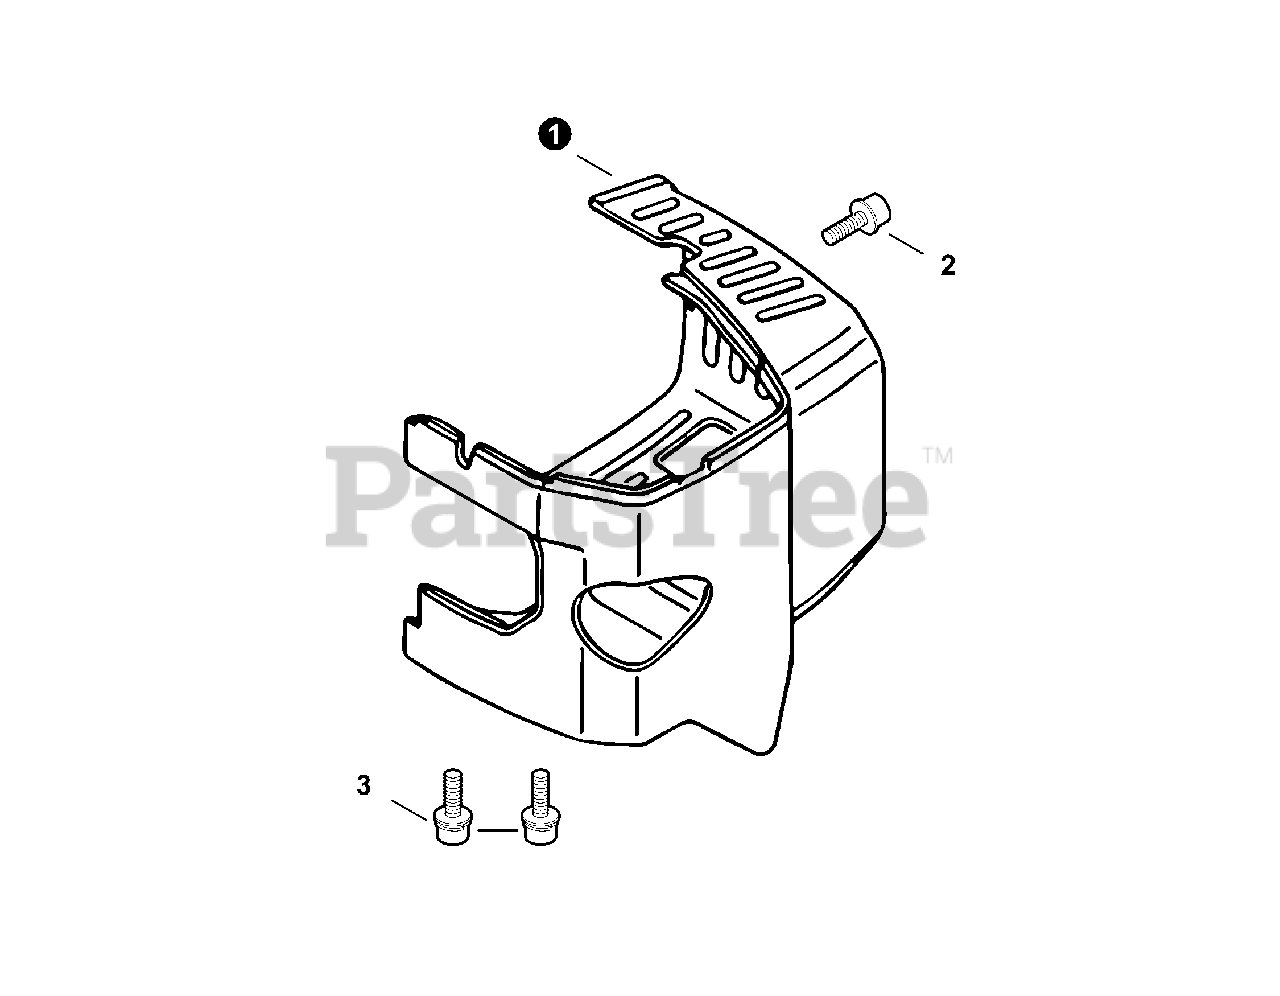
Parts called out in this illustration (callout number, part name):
1	COVER, ENGINE
2	BOLT 4×8
3	SCREW 4×18
